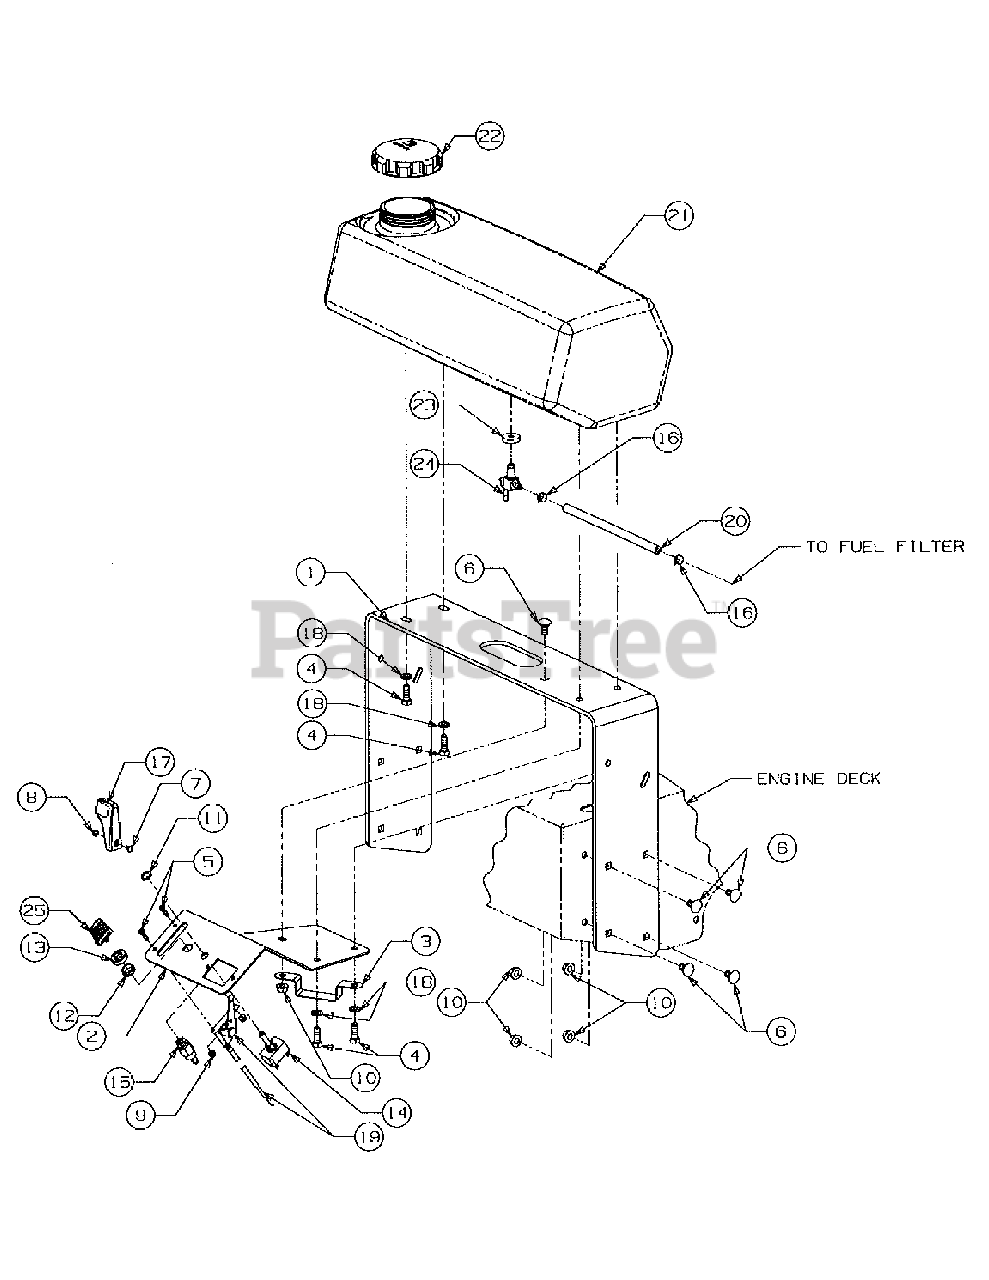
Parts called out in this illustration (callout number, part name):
1	Support Lower Handle
1	Washer, Lock 3/8
2	Panel, Control
2	Graphic, Control Panel
3	Bracket, Cable Retainer
4	Screw, Hex Cap, 3/8-16 x 1.0 Lg Gr 5
5	Screw, Pan Hd Cutting, #10-24 x .75 Lg
6	Bolt, Sht Nk Carriage, 3/8-16 x .75 Lg Gr 5
7	Screw, Cross Rec Truss Hd, #8-32 x .38
8	Nut, Hex, #8-32
9	Nut, Hex Nylock, #10-24
10	Nut, Hex Flanged Lock, 3/8-16
11	Nut, Hex, 1/2-27 x .100Thk
12	Nut, Ignition Switch, 5/-32
13	Cap, Ignition Switch
14	Switch, PTO
15	Switch, Ignition
16	Clamp, Hose
17	Knob, Throttle Control
19	Control Cable
20	Fuel Line
21	Fuel Tank
22	Fuel Cap
23	Grommet, Shutoff Valve
24	Valve, Fuel Shutoff
25	Key, Ignition
